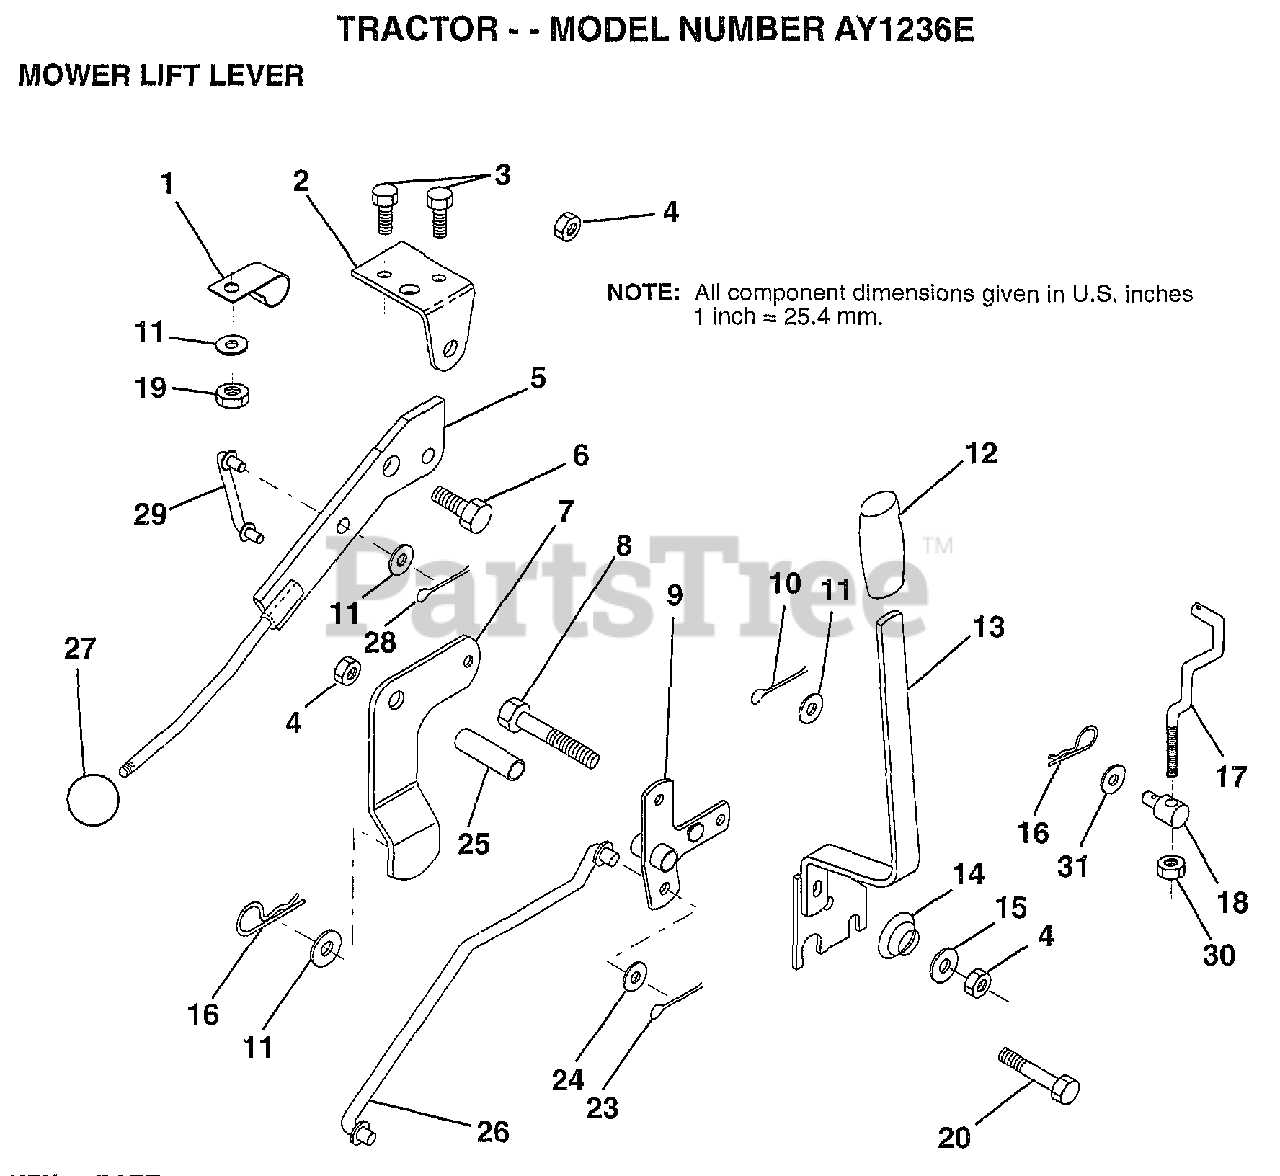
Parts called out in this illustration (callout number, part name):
1	"CLIP,INSULATOR"
2	BRKT CLUTCH
3	BOLT HXHD FIN
5	LEVER.ASM.CLUTCH
6	"BOLT, SHOULDER LT"
7	MWR CLUTCH ARM AS
8	BOLT
9	"BELLCRANK,LIFT"
10	COTTER PIN
11	WASHER
13	HANDLE.ASM.LIFT
14	SPRING COMPRESSIO
15	WASHER T
16	SPRING.RETAINER
17	"LINK,LIFT FRT"
18	TRUNION ADJ
20	BOLT
23	PIN COTTER 1/8
25	TUBE SPACER
26	ROD LIFT MOWER
27	KNOB T(3/8 HOLE)
29	CLUTCH LINK
30	NUT
31	WASHER
